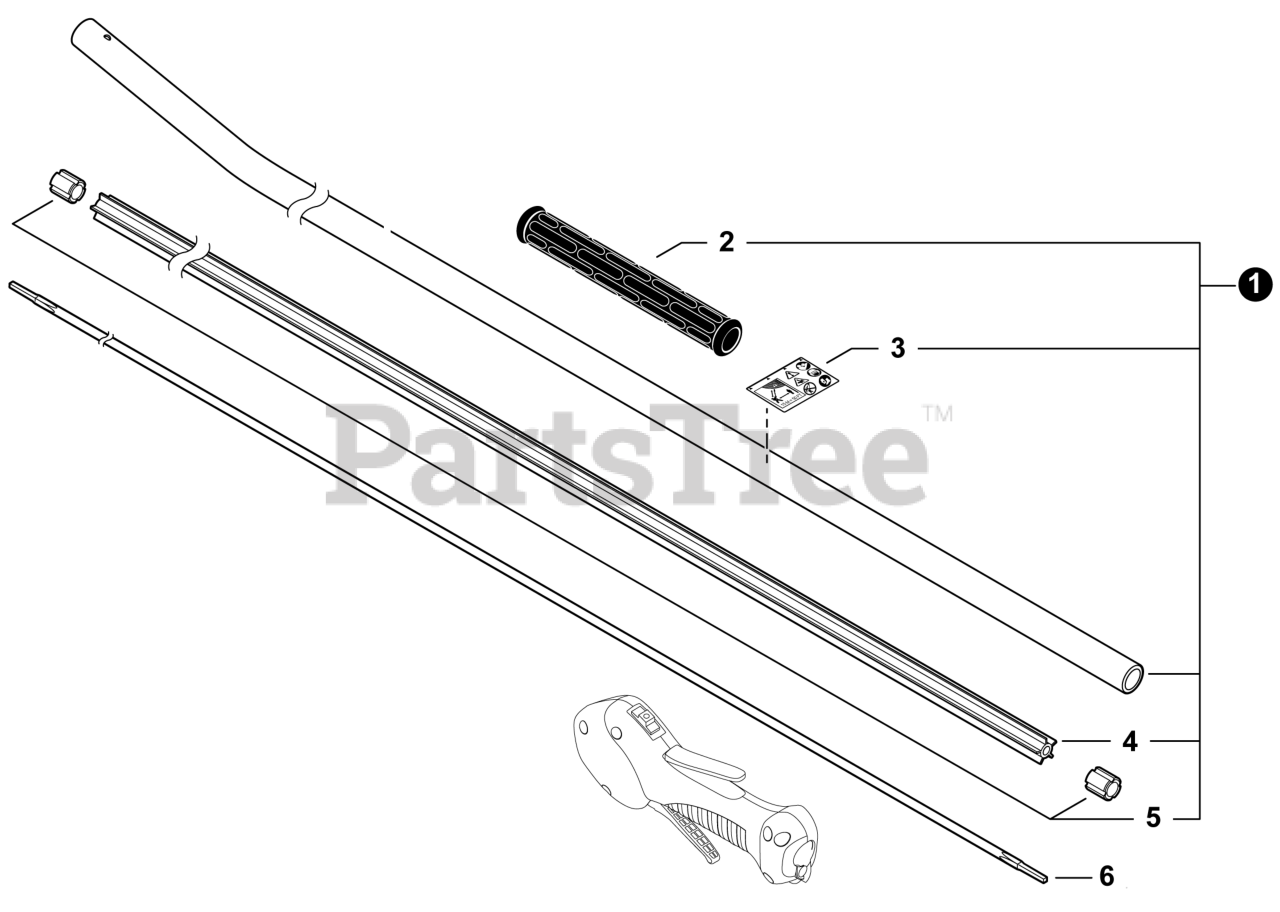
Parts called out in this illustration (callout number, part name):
1	MAIN PIPE ASSY
2	GRIP, FRONT
3	LABEL - CAUTION ISO
4	LINER - FLEXIBLE
5	STOPPER
6	DRIVESHAFT - FLEXIBLE
